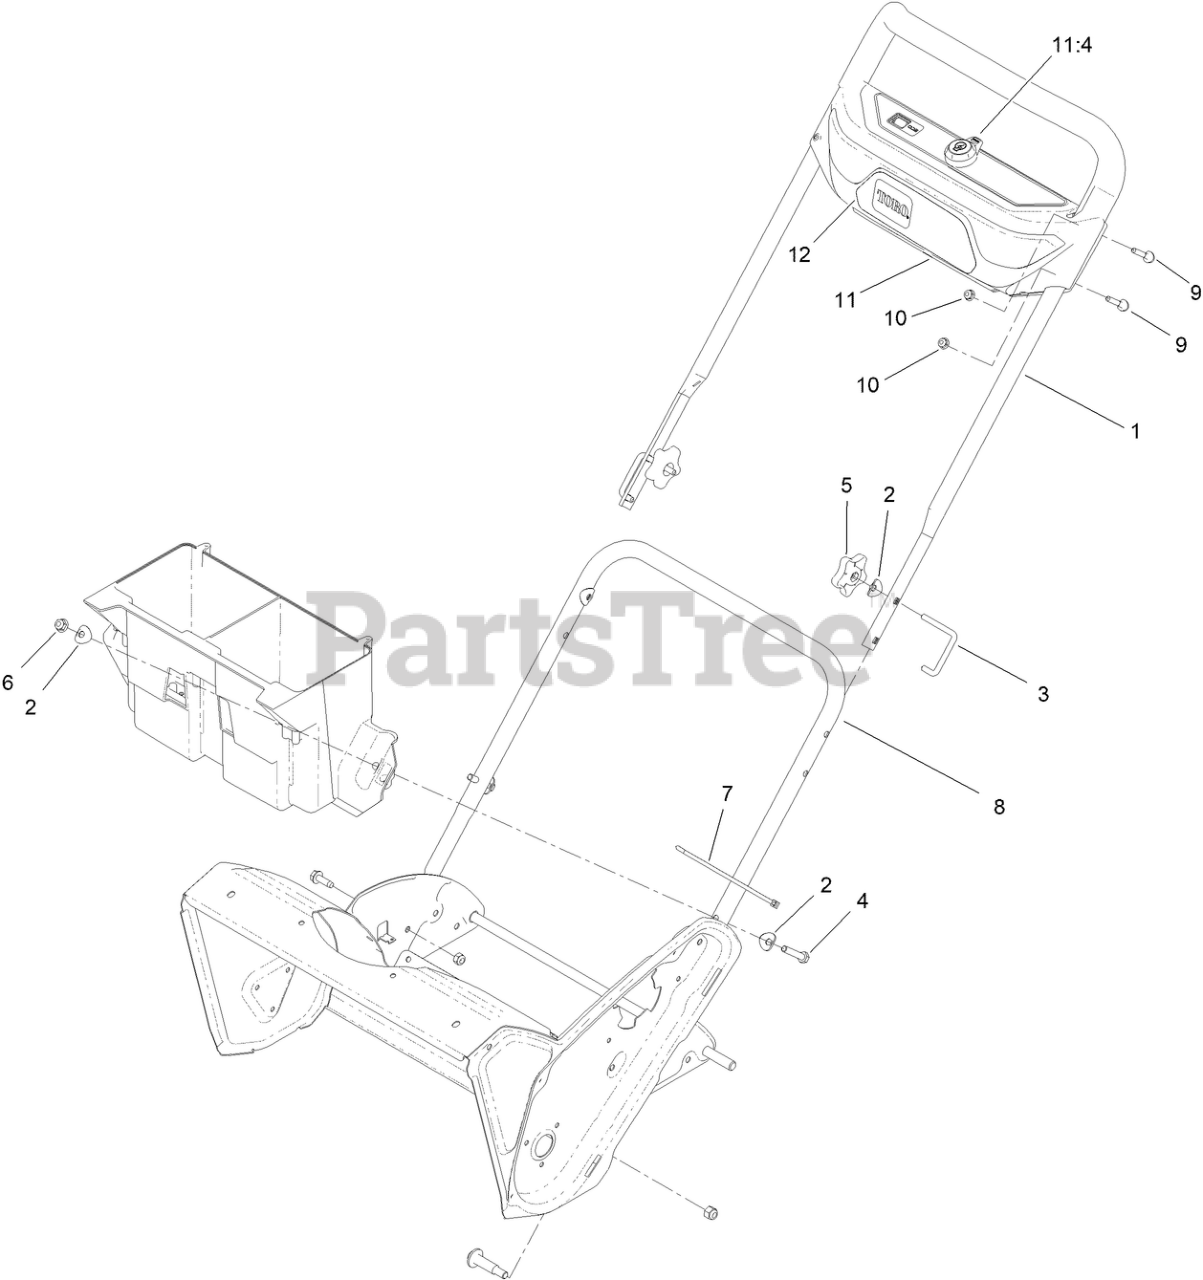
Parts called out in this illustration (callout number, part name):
1	HANDLE BAR-UPPER ASM
2	WASHER-CUP
3	LOCK-HANDLE
4	SCREW-HH
5	KNOB-HANDLE
6	NUT-FLANGE, NI
7	TIE-CABLE
8	HANDLE-LOWER
9	SCREW-HANDLE
10	NUT-HF
11	DASH PANEL ASSEMBLY, 60V SNOW
11:4	KEY-BAIL
12	DECAL - CONSOLE
